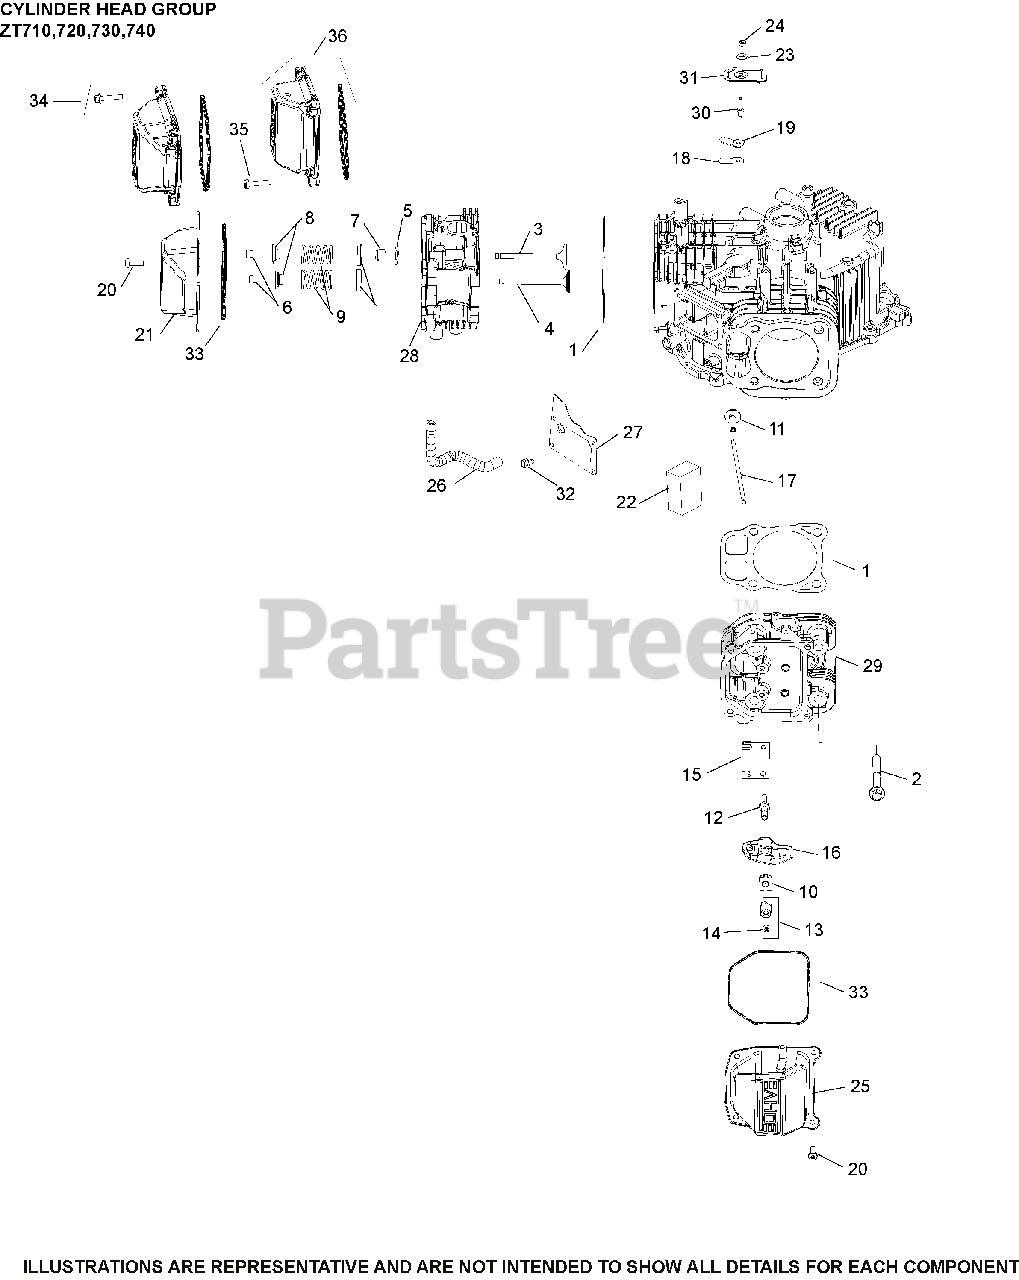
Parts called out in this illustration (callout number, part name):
1	KIT, CYLINDER HEAD GASKET
2	SCREW, FLG M10X1.5X90
3	VALVE, INTAKE
4	VALVE, EXHAUST
5	SPACER (.010")
6	KIT, RETAINER
7	SEAL, VALVE BAND
8	CAP, VALVE SPRING
9	SPRING, VALVE - USE 25 089 17-S
10	PIVOT, ROCKER ARM
12	STUD, ROCKER
13	HEX NUT ASSEMBLY
14	SCREW, SET
15	PLATE, GUIDE
16	ARM, ROCKER
17	ROD, PUSH
18	REED, BREATHER
19	RETAINER, REED
20	SCREW, PAN HEAD USE 25 086 660-S
21	COVER, ROCKER STAMPED STEEL
22	FILTER, BREATHER
23	WASHER, SEALING
24	NUT, LOCK M5X.8
25	COVER, ROCKER STAMPED STEEL
26	HOSE, BREATHER
27	COVER, BREATHER MEDIA
28	CYLINDER HEAD (#1)
29	CYLINDER HEAD (#2)
31	COVER, BREATHER REED
